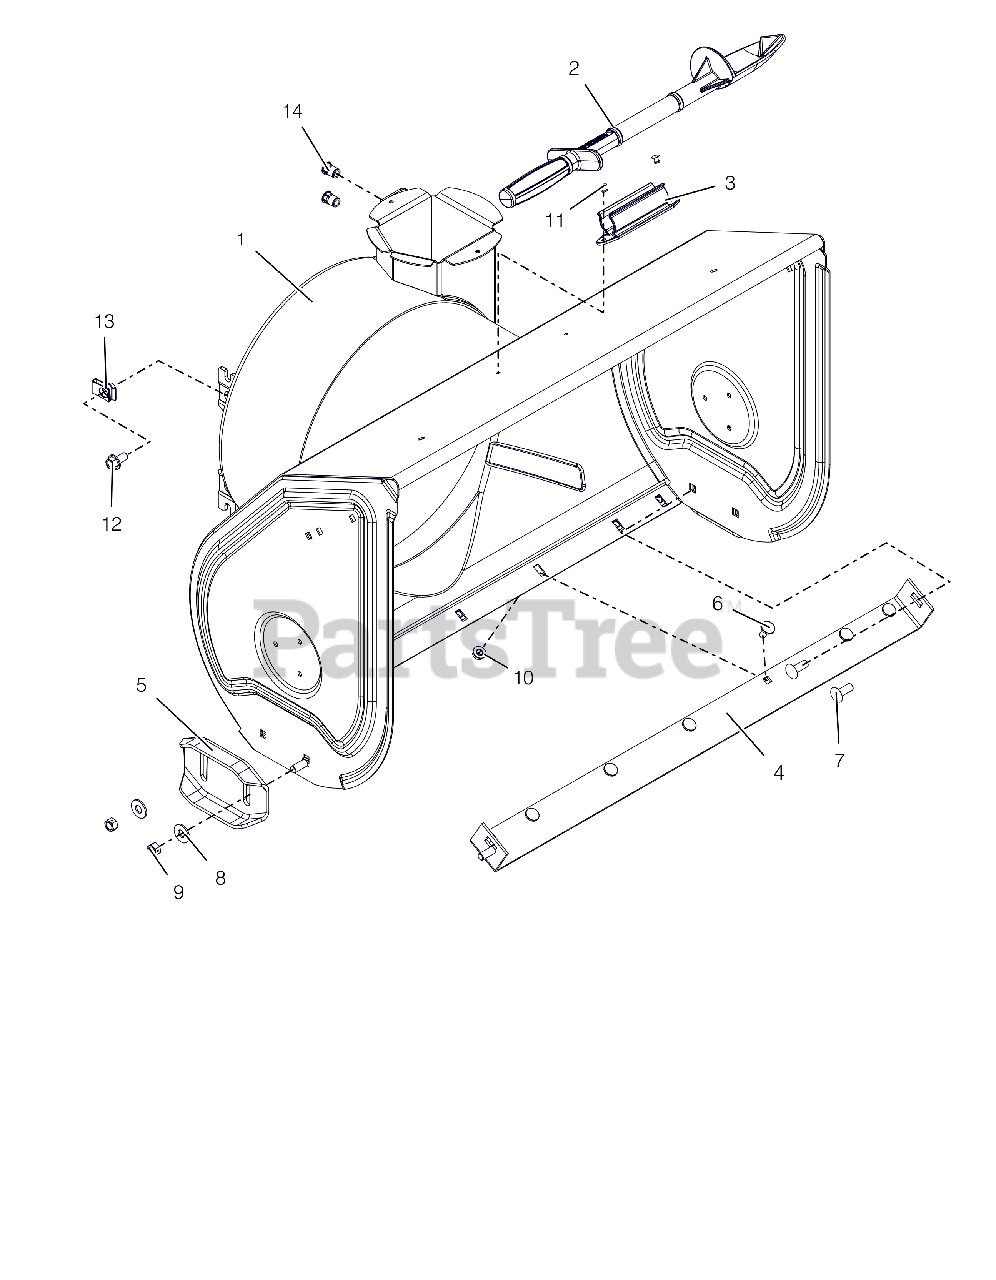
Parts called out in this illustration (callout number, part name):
1	BLOWER HOUSING W/DECAL 30"
2	DEVICE, SNOW CLEAN OUT
3	MOUNT, SNOW CLEAN OUT
4	BLADE, SCRAPER-30"
5	SKID SHOE, REVERSIBLE - ORANGE
6	BOLT, MODIFIED HEAD CARRIAGE
7	@BLT-RDHDSHSQNK.38-16X1.0 G5YZ
8	@WSHR-FL-STL.438X1.00X.083 YWZ
9	@NUT-LK-CTR .38-16 YWZC
10	@NUT-LK-TOP-FLG .31-18 YWZC
11	RVT-POP .187 YZ
12	BLT-SERHFWH .38-16X.75 YWZC
13	NUT-RTNR .375-16X.37
14	NUT, THREADED INSERT .38-16
